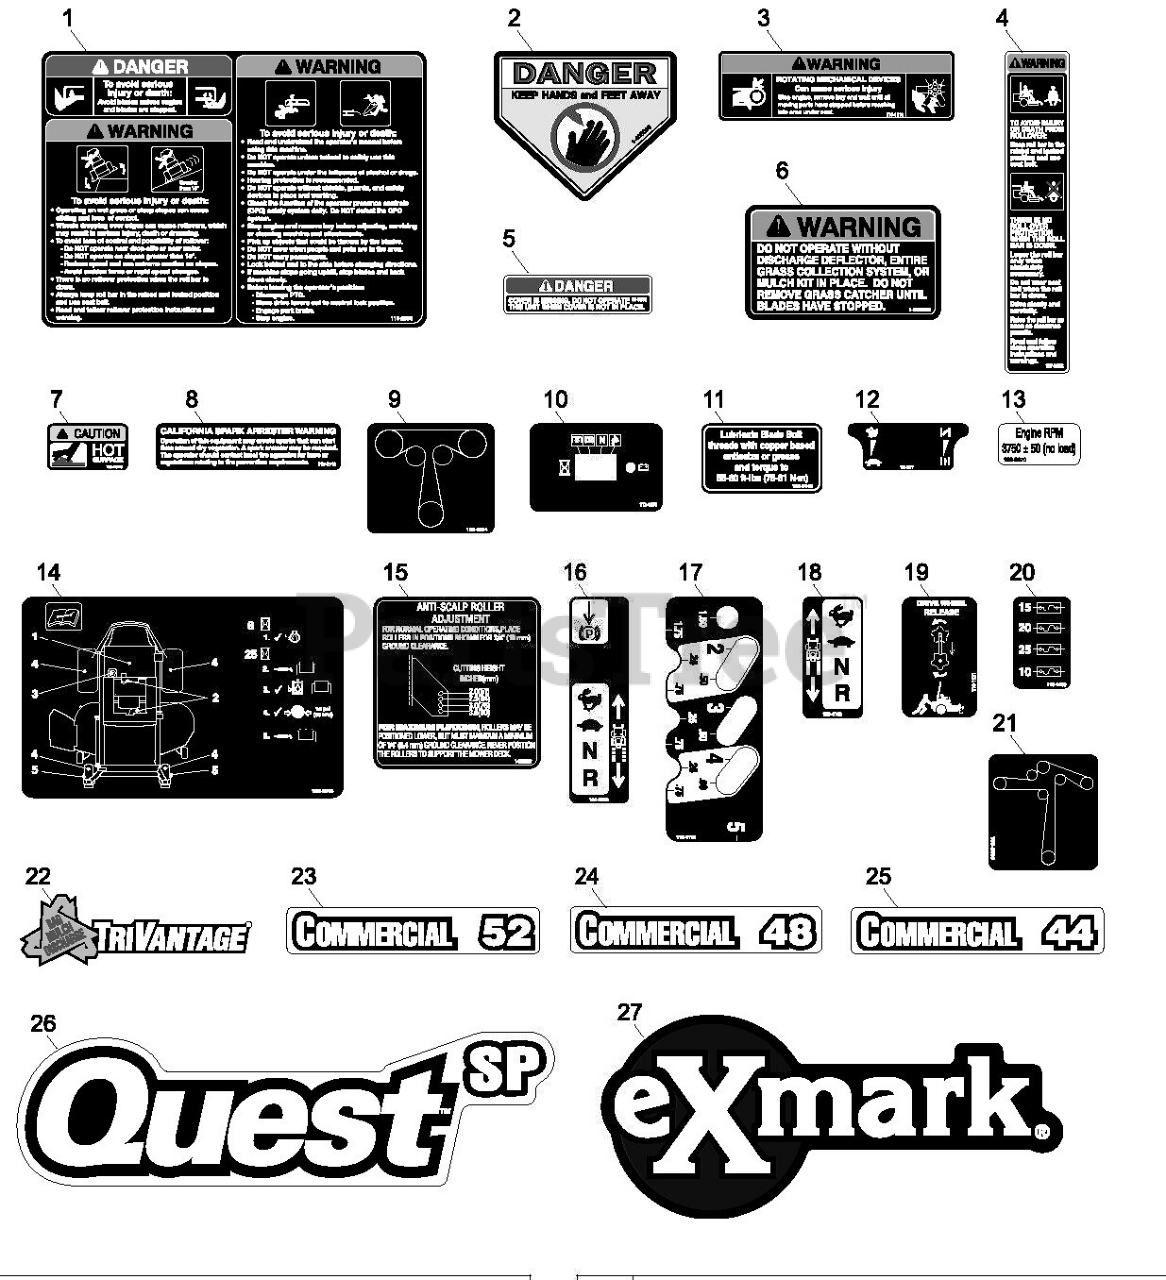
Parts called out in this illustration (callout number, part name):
1	DECAL-CONSOLE
2	DECAL-DANGER
3	DECAL,BELT DRIVE
4	DECAL-WARNING, FOLDING RO
5	DECAL-COVER, MISSING
6	DECAL-WARNING, DISCHARGE
7	DECAL-CAUTION
8	DECAL-ARRESTER, SPARK
9	DECAL-ROUTING, BELT
10	DECAL-Z HOUR METER
11	DECAL,BOLT TORQUE
12	DECAL-THROTTLE
14	DECAL-SERVICE AID
15	DECAL,ANTISCALP
16	DECAL-CONTROL BRAKE
17	DECAL,HEIGHT OF CUT
18	DECAL-MOTION CONTROL
19	DECAL,DRIVE RELEASE
20	DECAL,FUSE BLOCK
21	DECAL-ROUTING, BELT
23	DECAL,COMMERCIAL 52
24	DECAL,COMMERCIAL 48
25	DECAL,COMMERCIAL 44
26	DECAL-QUEST SP LOGO
27	DECAL, EXMARK LOGO
